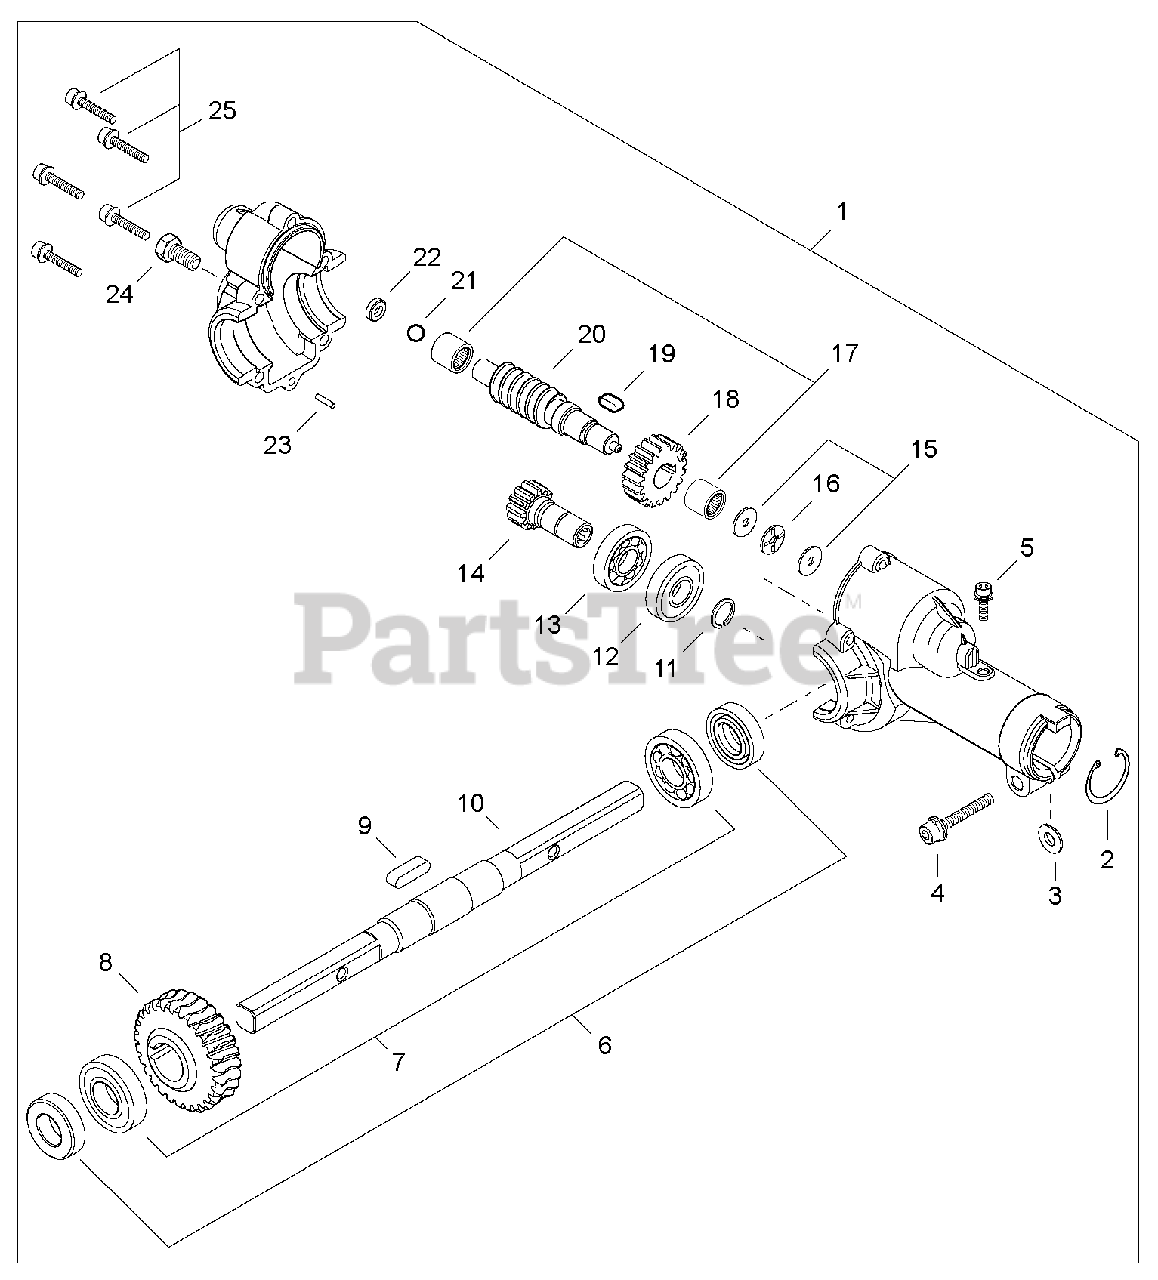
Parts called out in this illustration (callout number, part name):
1	GEAR CASE ASSY
2	RING, RETAINING Ø24
3	D-WASHER
4	BOLT 6×30
5	BOLT 5×12
6	SEAL, OIL 17
7	BEARING, BALL 6003
8	GEAR, WORM WHEEL
9	KEY, WOODRUFF
10	SHAFT, GEAR
11	RING, SNAP Ø12
12	BEARING, BALL 6901
13	BEARING, BALL 6901
14	GEAR, SPUR 12 TOOTH
16	BEARING, THRUST
17	BEARING, NEEDLE 10
18	GEAR, SPUR 19 TOOTH
19	KEY, WOODRUFF
20	GEAR, WORM
23	PIN, LOCATING 4×20
24	BOLT 8×10
25	BOLT 5×20
